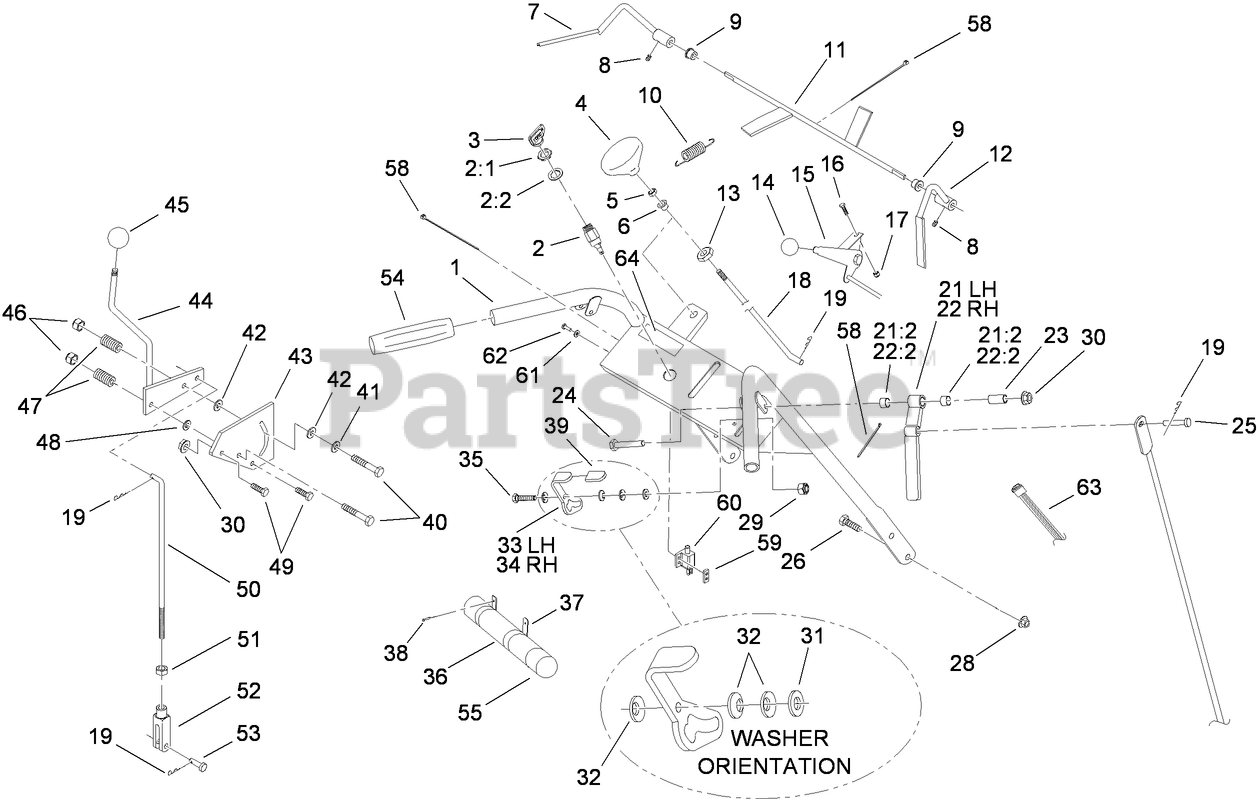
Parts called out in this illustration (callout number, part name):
1	HYDRO HANDLE ASM
2	SWITCH-ON / OFF
2:1	NUT-HH
2:2	WASHER-TOOTH, INTERNAL
3	KEY-IGNITION
4	Knob-Push / Pull
5	NUT-JAM
6	Bearing-Nylon
7	LH OPERATOR PRESENCE CONTROL LEVER ASM
8	SCREW-SET
9	BUSHING-NYLON
10	SPRING-EXTENSION
11	ROD-CONTROL, OPERATOR PRESENCE
12	RH OPERATOR PRESENCE CONTROL LEVER ASM
13	NUT-PUSH
14	KNOB-BALL
15	THROTTLE CABLE ASM
16	BOLT-CARR
17	NUT-LOCK, NI
18	Linkage-Blade
19	PIN-COTTER
21	LH Drive Lever ASM
21:2	BUSHING-SLEEVE
22	RH Drive Lever ASM
22:2	BUSHING-SLEEVE
23	Bushing-Lever, Drive
24	SCREW-HH
25	Pin-Clevis
26	SCREW-HHF
28	NUT-HF
29	NUT-LOCK, NI
30	NUT-HF
31	WASHER-FLAT
32	WASHER-SPRING
33	LH LATCH GRIP ASM
34	RH LATCH and GRIP ASM
35	SCREW-HH
36	TUBE-MANUAL
37	CLAMP-R
38	SCREW-HWHTF
39	GRIP-LATCH
40	SCREW-HH
41	Washer-Friction
42	Washer-Friction
43	PLATE-LEVER, SHIFTER
44	LEVER-SHIFT
45	KNOB-BALL
46	NUT-LOCK, NI
47	SPRING-COMPRESSION
48	WASHER-PLAIN
49	SCREW-HH
50	Rod-Control, Speed
51	NUT-JAM
52	YOKE-ADJUSTABLE
53	PIN-CLEVIS
54	GRIP-FOAM
55	CAP-HOUSING
58	TIE-CABLE
59	PLATE-TAPPED
60	SWITCH-OPEN, NORMALLY
61	WASHER-FLAT
62	SCREW-PPH
63	Harness-Wiring
64	DECAL-ARRESTER, SPARK
